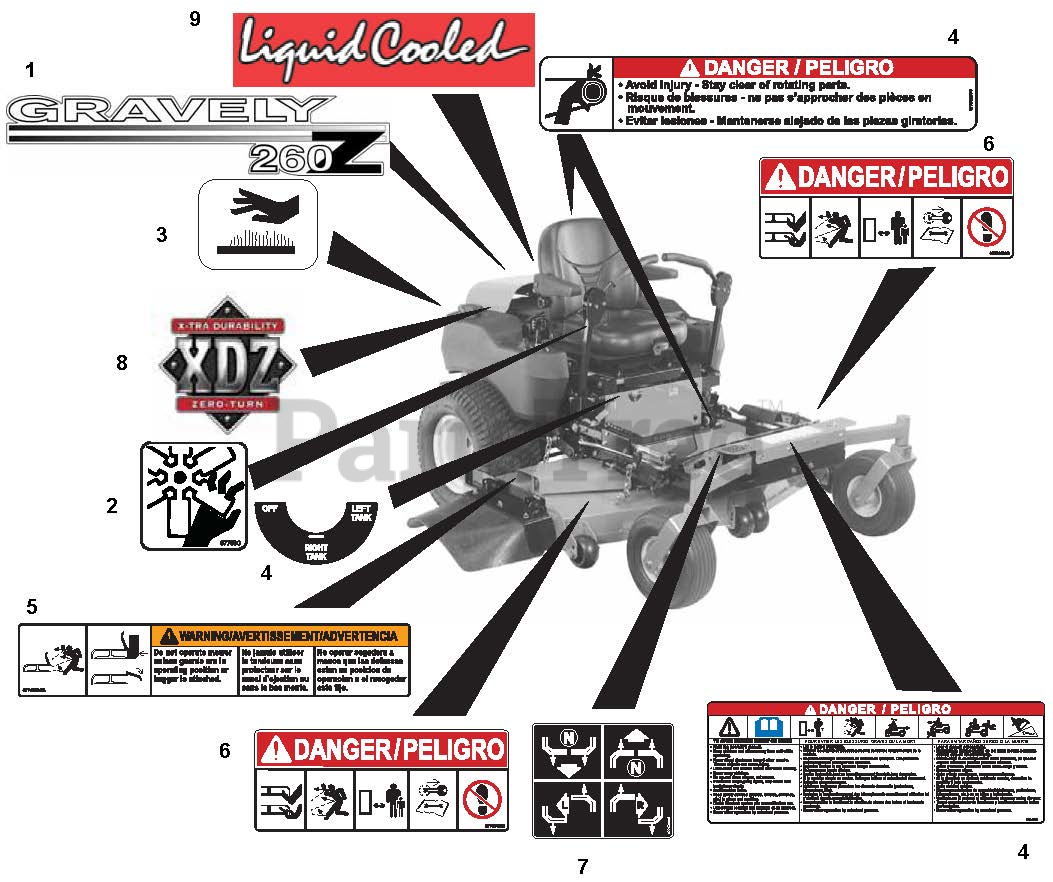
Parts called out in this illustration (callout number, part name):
1	Decal, PM-252Z Hood
1	Decal, PM-260Z Hood
1	Decal, PM-272Z Hood
1	Decal, PM-266Z Hood
2	Decal, Danger Fan
3	Decal-Hot Surface
4	Set, Decal-Common Danger/Fuel
5	Decal, Warning
6	Decal, Mower Pan Head Danger
7	Decal-Instructional
8	Decal, XDZ
9	Decal, Liquid Cooled
